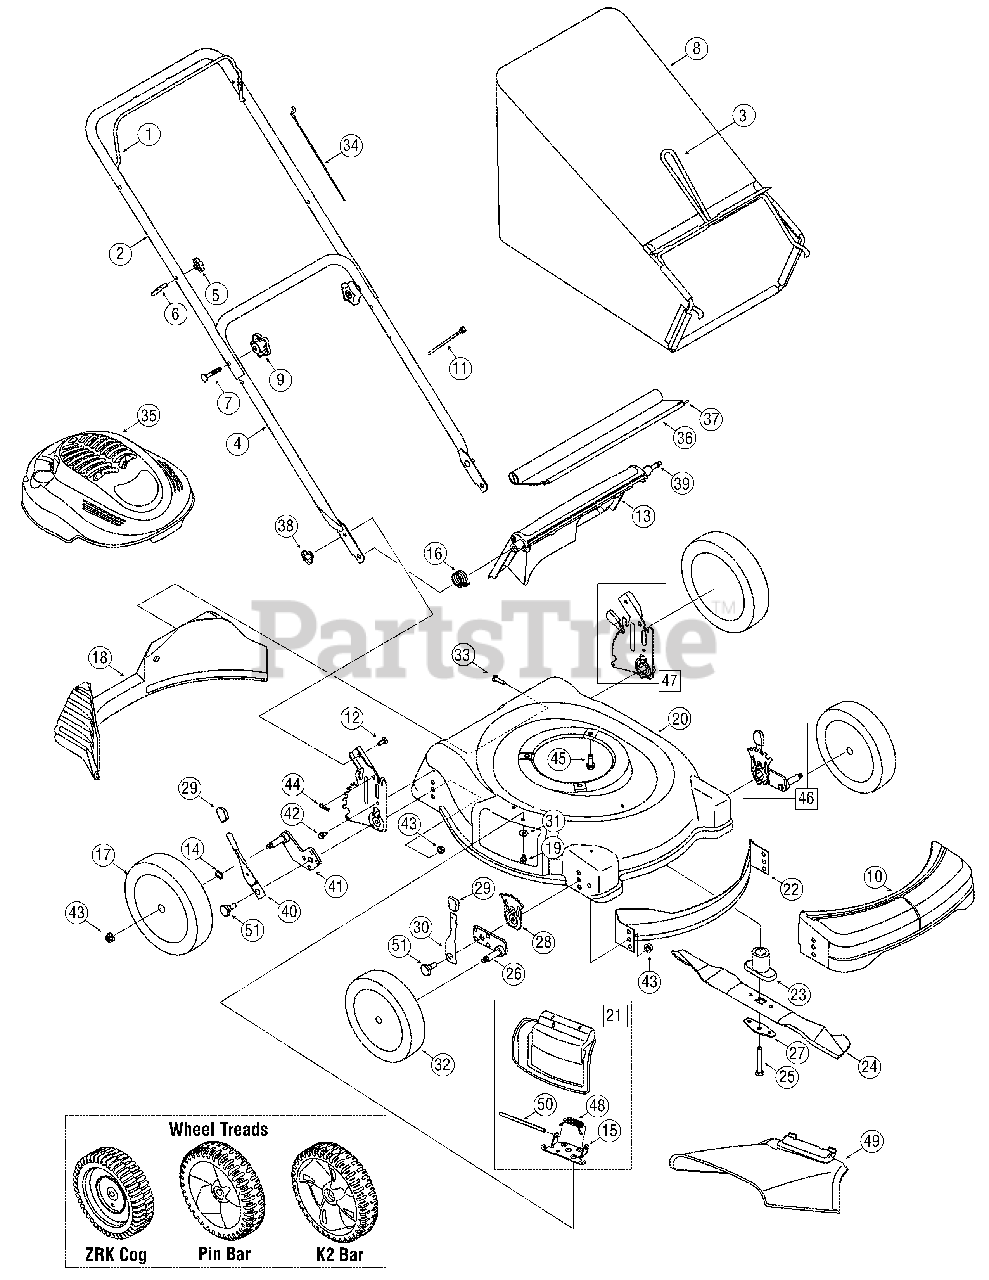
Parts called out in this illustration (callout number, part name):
5	Wing Nut
6	Rope Guide
7	Carriage Bolt, 5/16-18 x 2
8	Grass Bag Assembly
9	Hand Knob
10	Front Cover
11	Cable Tie
12	Carriage Bolt ,1/4-20
13	Rear Discharge Door
14	Wave Washer
15	Deflector Chute Adaptor
16	Torsion Spring - RH
17	Rear Wheel, 8 x 1.8, K2 Bar
18	Rear Baffle
19	Screw, 1/4-20 x .500
22	Front Baffle
23	Blade Adapter
24	Mulching Blade
25	Hex Screw , 3/8-24 x 2.5
26	Pivot Arm Assy RH (7" wheel)
26	Pivot Arm Assy RH (8" wheel)
27	Blade Bell Support
28	Front Adjustment Plate
29	Adjustment Lever Knob
30	Spring Lever Assembly
31	Bell Washer
32	Front Wheel, 7 x 1.8, K2 Bar
33	Screw, 1/4-15 x 1.000
34	Control Cable 40 inch
34	Control Cable 53 inch
35	Engine Shroud
36	Trailshield
37	Trailshield Wire
38	Wing Nut, 1/4-20
39	Rear Door Pivot Rod
40	Spring Lever
41	Pivot Arm Assembly - RH
42	AB Screw
43	Flange Lock Nut, 3/8-16
44	Hairpin Clip
45	TT Sems Screw, 3/8-16 x 1.0
46	Ht. Adj. Assy. Front LH (7" wheel)
46	Ht. Adj. Assy. Front LH (8" wheel)
47	Rear Handle Bracket Assy. - LH
48	Torsion Spring
49	Side Chute
50	Hinge Pin
51	Shoulder Screw
